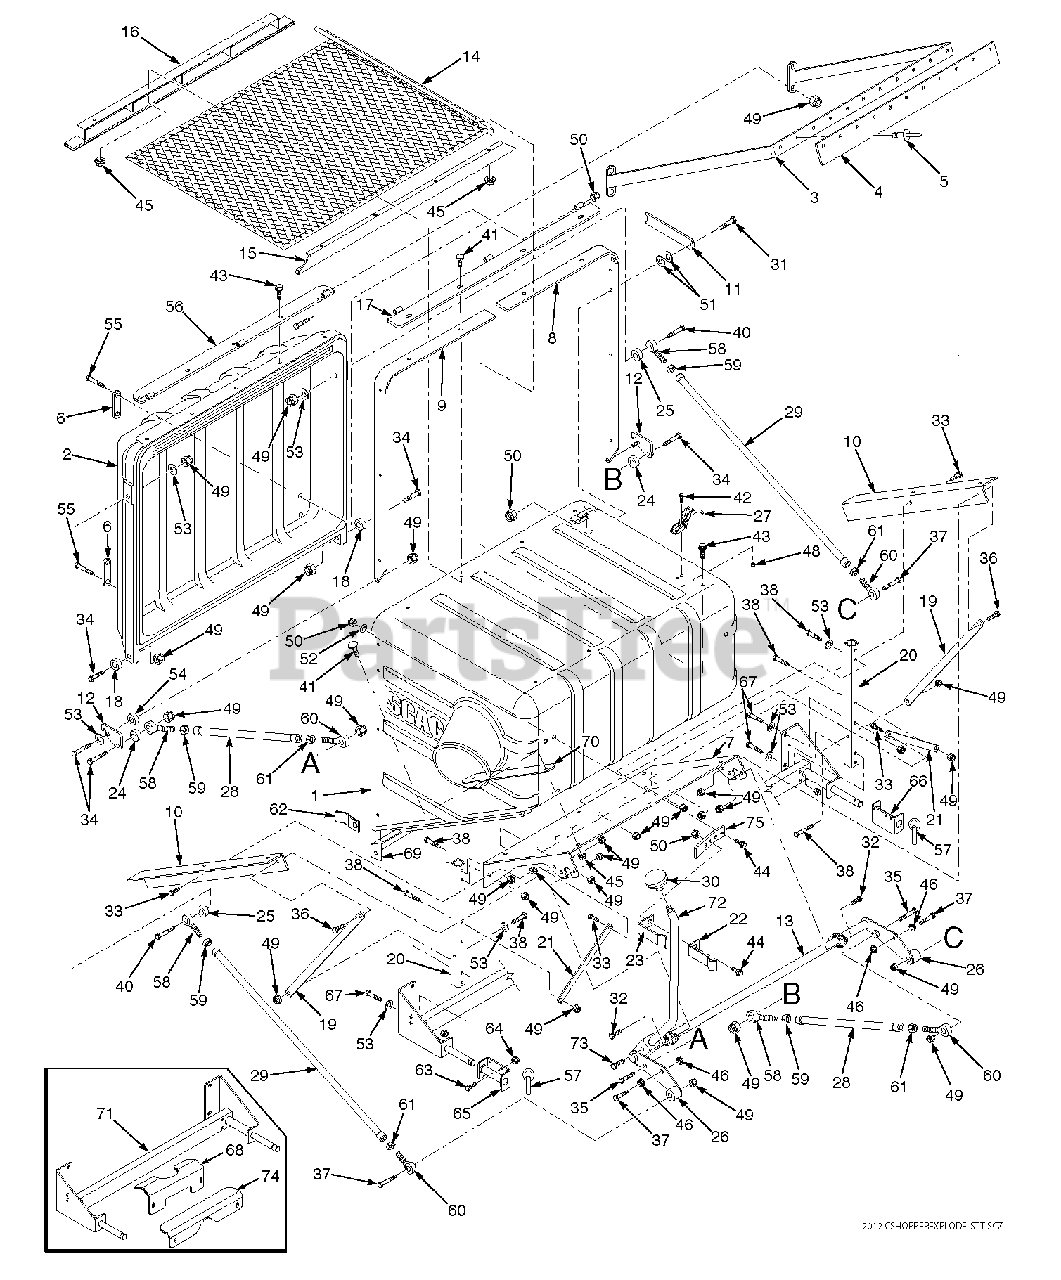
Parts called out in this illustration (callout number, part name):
1	Hopper, GC-STT-CS
2	Door, GC-CS
3	Sweeper Weldment, GC-CS
4	Pad, Rubber
5	Pop Rivet, 3/16 x .652
6	Plate, Stiffener
7	Support Frame, Hopper
8	Hinge Bracket, LH
9	Hinge Bracket, RH
10	Bracket, Hopper Support
11	Latch, Door Prop
12	Plate, Latch
13	Bellcrank Weldment, Upper
14	Debris Screen Weldment
15	Screen Support Weldment, Rear
16	Screen Support Weldment, Front
17	Hinge Weldment, Hopper
18	Spacer
19	Brace Stiffener, Long
20	Tube, Upright
21	Brace, Engine Mount
22	Latch, Dump Rod Inner
23	Latch, Dump Rod Outer
24	Spacer
25	Spacer
26	Spacer
27	Latch, Hood
28	Linkage Assembly, Lower
29	Linkage Assembly, Upper
31	Bolt, Hex Head 5/16-18 x 1-1/4"
32	Bolt, Hex Head 3/8-16 x 3/4"
33	Bolt, Hex Head 3/8-16 x 1"
34	Bolt, Hex Head 3/8-16 x 1-1/2"
35	Bolt, Hex Head 3/8-16 x 1-3/4"
36	Bolt, Hex Head 3/8-16 x 1-1/4"
37	Bolt, Hex Head 3/8-16 x 2"
38	Bolt, Hex Head 3/8-16 x 2-1/4"
39	Bolt, Hex Head 5/16-18 x 3-1/2"
40	Bolt, Hex Head 3/8-16 x 3-1/2"
41	Bolt, Carriage 5/16-18 x 1"
42	Screw, #10-32 x 1/2"
43	Cap Screw, 5/16-18 x 3/4" Serr. Flan.
44	Cap Screw, 5/16-18 x 1" Serr. Flan.
45	Nut, 5/16-18 Serrated Flange
46	Nut, 3/8-16 Serrated Flange
47	Nut, 3/8-16 UNC Jam
48	Nut, #10-32 Elastic Stop
49	Nut, 3/8-16 Elastic Stop
50	Nut, 5/16-18 Elastic Stop
51	Washer, Special Wave
52	Washer, 5/16-.375 x .875 x .083 Flat
53	Washer, 3/8-.931 x .938 x .105 Flat
54	Bushing, Hopper Latch GC-CS
55	Bolt, Hex Head 3/8-16 x 3"
56	Hinge Weldment, Door
58	Rod End Male, 3/8-24 LH Thread
59	Nut, 3/8-24 UNF LH Thread
60	Rod End Male, 3/8-24 RH Thread
61	Nut, 3/8-24 UNF RH Thread
62	Alignment Bracket, GC-CS
63	Bolt, Hex Head 3/8-16 x 1"
64	Nut, 3/8-16 Elastic Stop
65	Hitch Bracket Weldment
66	Hitch Bracket Weldment, Floating
67	Bolt, Hex Head 3/8-16 x 3-3/4"
68	Support Bracket, Catcher STT
69	Bracket, Lower Stiffener
70	Retainer Strip, Hopper
71	Frame Weldment
72	Rod, Dump Lever GC-SCZ-CS
73	Bolt, Hex Head 5/16-18 x 1-3/4"
74	Support Bracket, GC
75	Mounting Bracket, Dump Handle Latch
